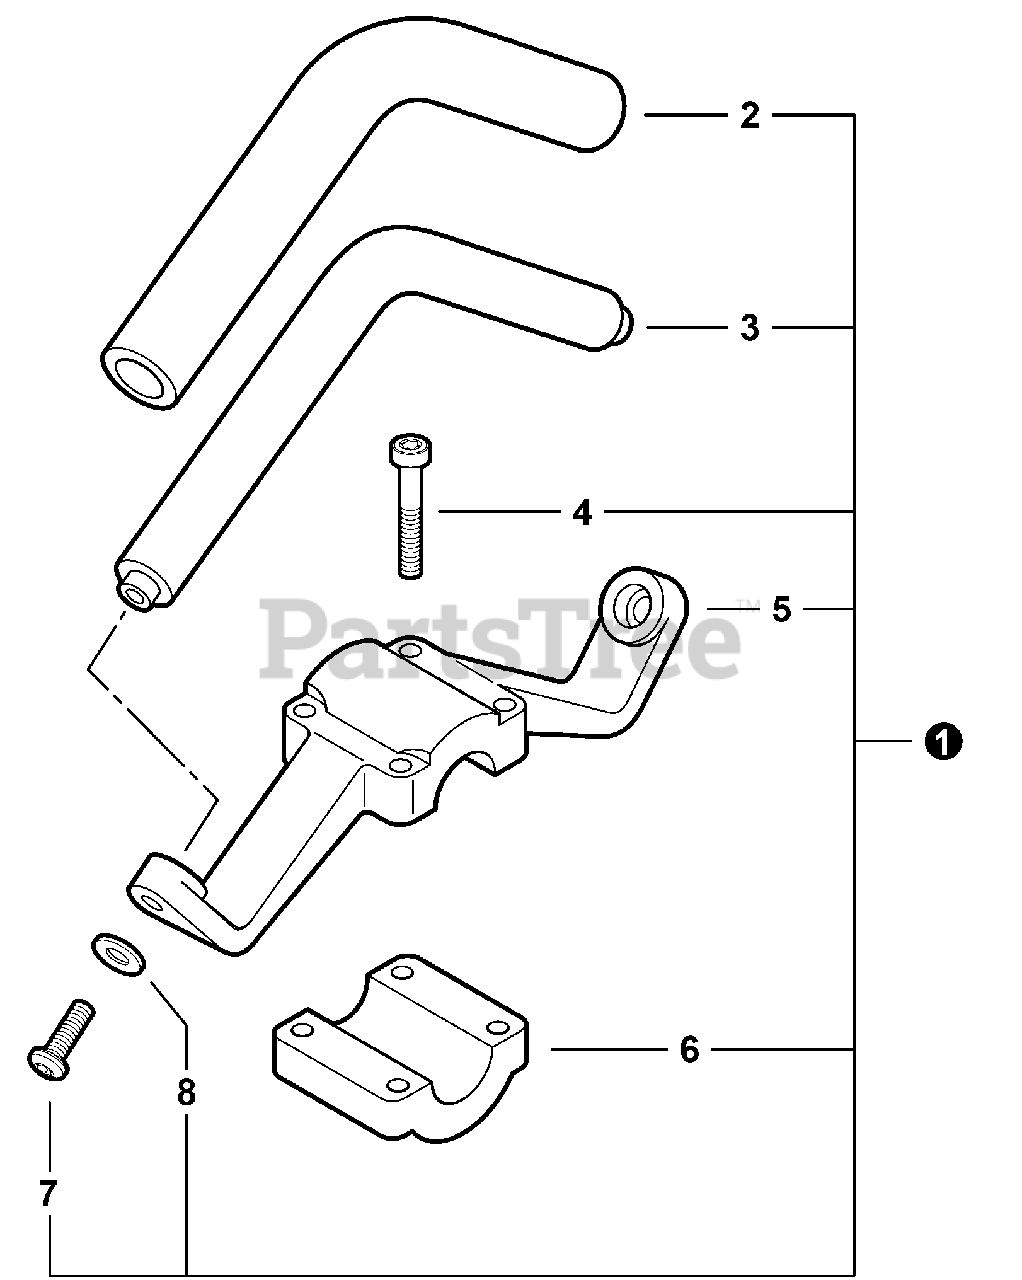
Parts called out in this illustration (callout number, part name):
1	HANDLE ASSY, SUPPORT
2	GRIP, HANDLE
3	HANDLE, SUPPORT
4	BOLT, TORX 5×30
5	BRACKET, HANDLE
6	BRACKET, HANDLE
7	BOLT, TORX 5×20
8	WASHER, FLAT 5.5×10×0.8
